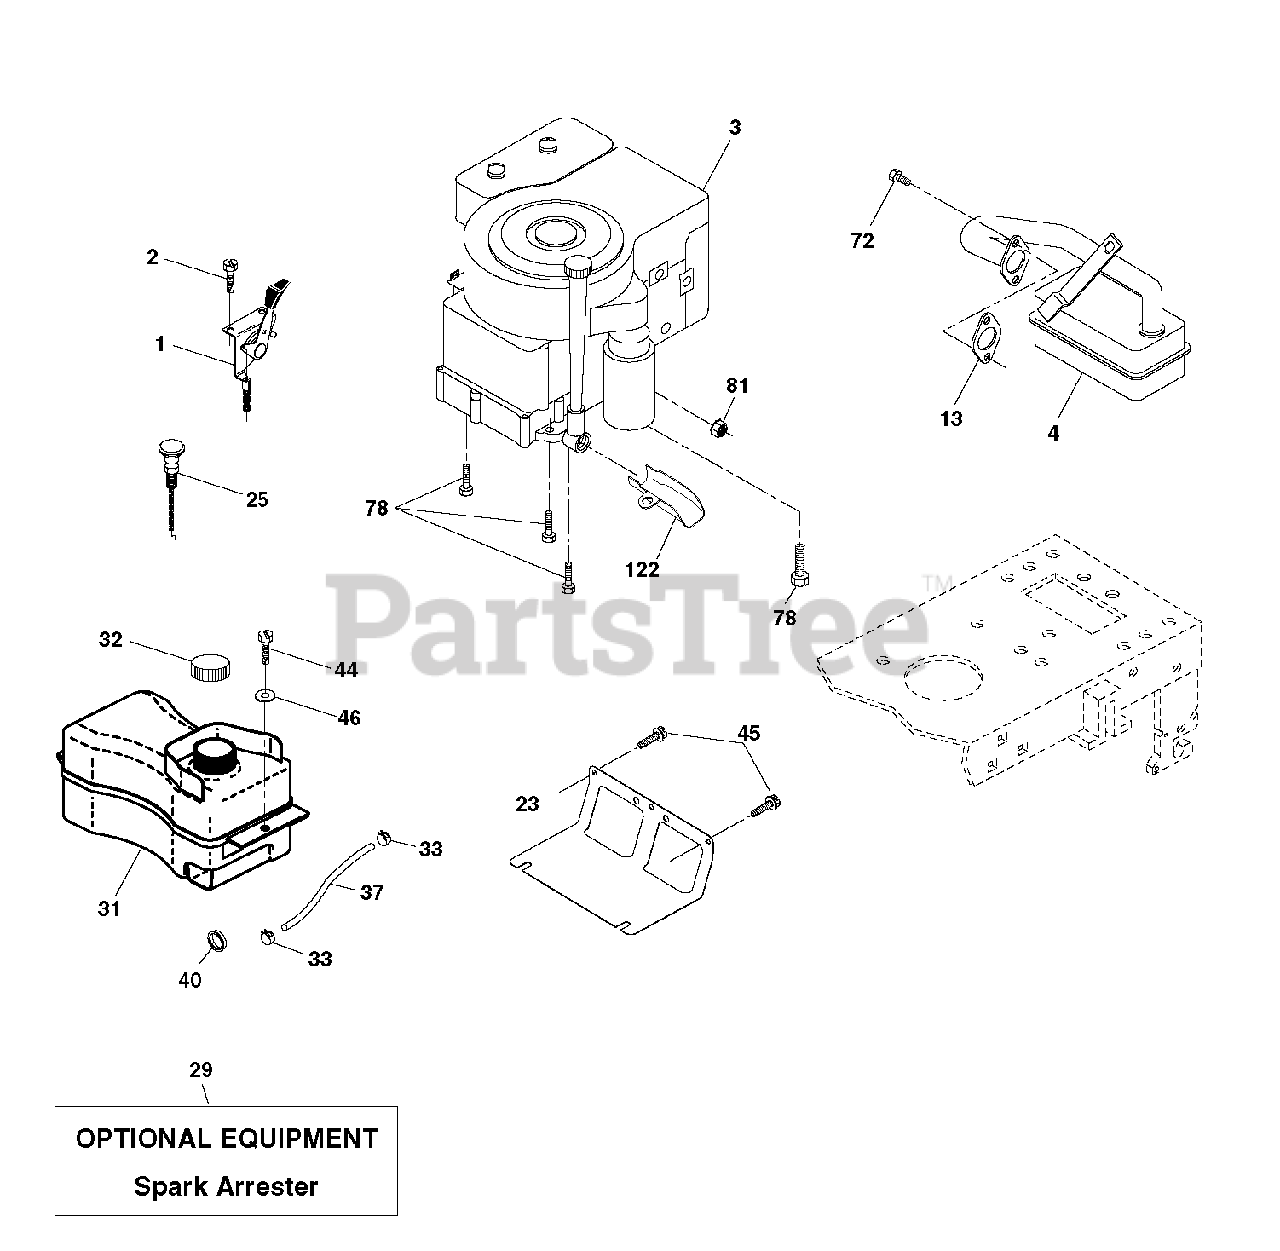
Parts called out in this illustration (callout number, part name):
1	CONTROL TH/CH FLAG
2	SCREW
13	REPL BY 532 27 22-93
23	SHEILD.BROWNING.DBR.GUARD
25	KNOB.ERGO.EXTENDED.RED (1 2)
29	ARRESTER SPARK (OPTIONAL)
32	CAP ASM.FUEL.2.25"FR.
44	SCREW HEXWSHR 1/4-20X3/4
45	SCREW, 3/8-16X3/4
72	SCREW.SOCKET HD.5/16-1
81	NUT
122	EXTENSION DRAIN OIL
